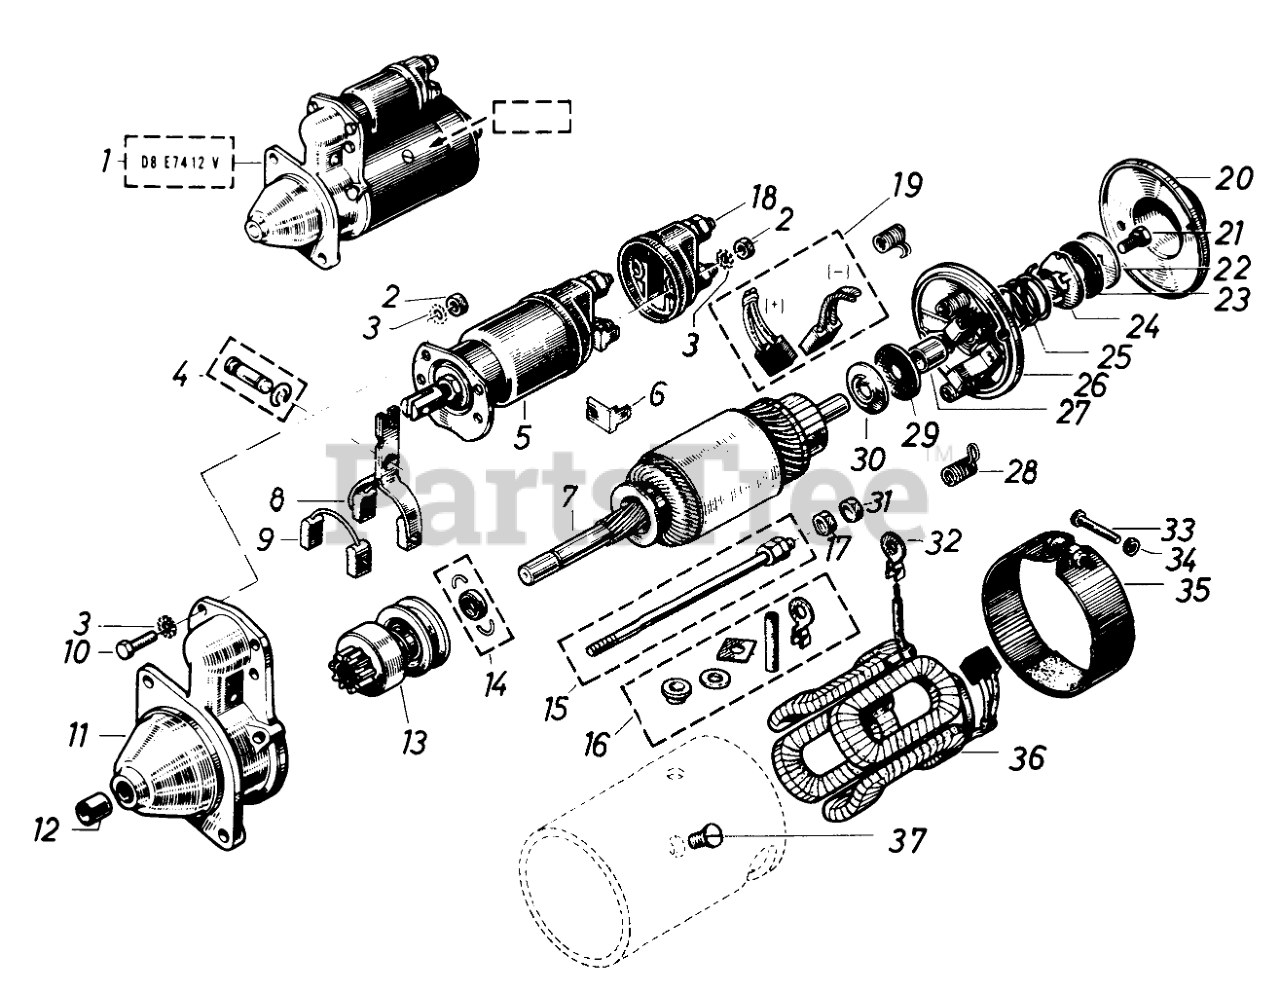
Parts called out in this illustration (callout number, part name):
1	Starter Assy.
3	Washer
4	Axle with Lock
5	Solenoid
6	Lever
7	Armature
8	Shift Fork
9	Jaws for Shift Fork
10	Screw
11	Drive Bearing Housing
12	Bushing
13	Drive Wheel
14	Pressure Ring
15	Screw Assy.
16	Set of Insulating Parts
18	Hood Assy.
19	Brush Set
20	Protection Cover
21	Screw
25	Spring
26	Commutator End Plate Assembly
27	Bushing
28	Spring
32	Cable Clamp
33	Screw
36	Field Winding
37	Screw
